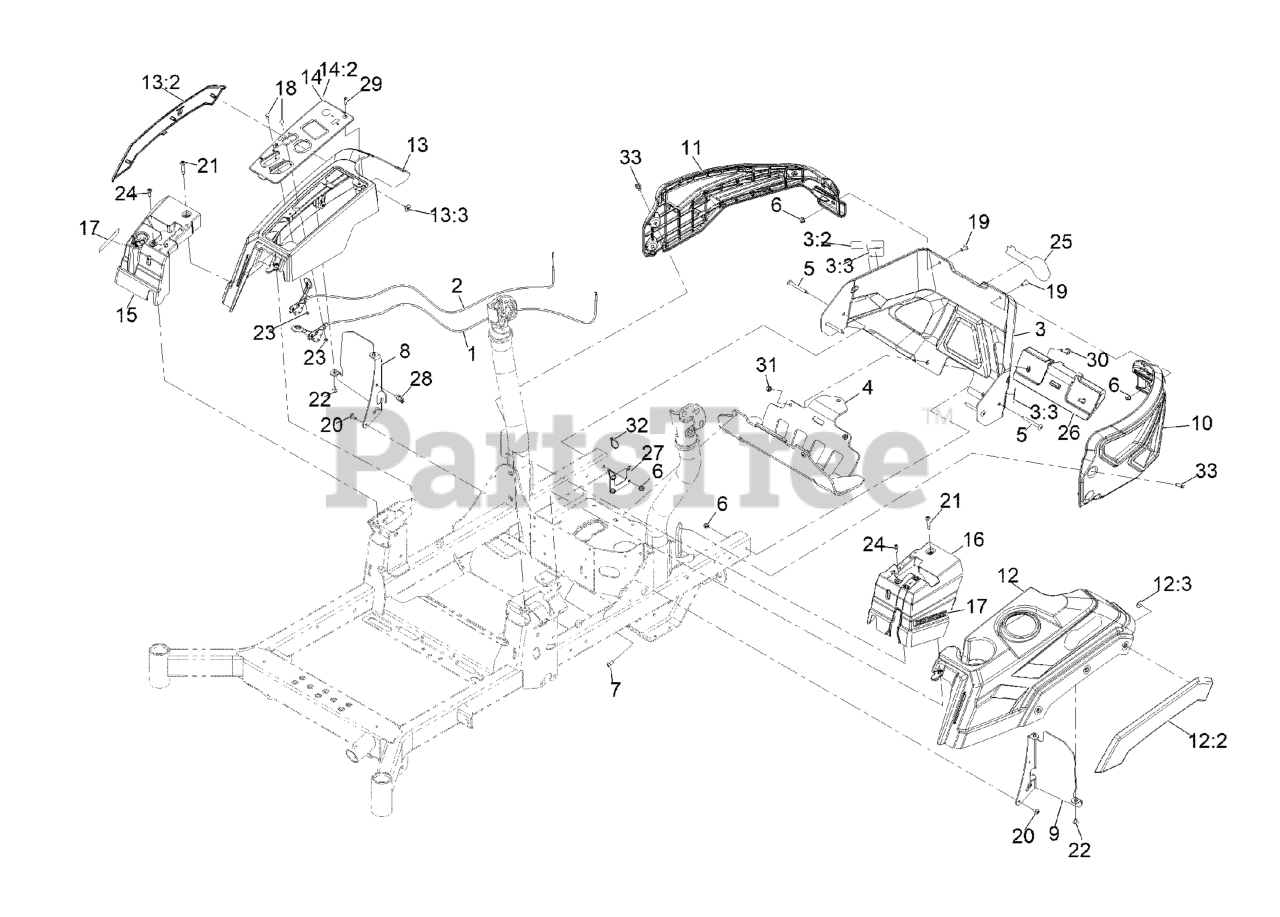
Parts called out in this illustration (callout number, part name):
1	CABLE, THROTTLE CONTROL
2	ASM,CHOKE CABLE
3	ASM, Rear Guard W/ Decals
3:2	DECAL-ARRESTOR, SPARK
3:3	DECAL-WARNING
4	GUARD, MUFFLER [BLACK]
5	SCREW-TORX
6	NUT-HF, NI
7	SCREW, TAPTITE
8	Bracket, Pod, Rt
9	Bracket, Pod, Lt
10	GUARD, UPPER, LT
11	GUARD, UPPER, RT
12	ASM, Pod Lt
12:2	Fender, Lt
12:3	Screw-Torx
13	ASM, POD RT
13:2	Fender, Rt
13:3	Screw-Torx
14	ASM-Control Panel W/Decal
14:2	DECAL-CONTROL PANEL
15	Cover, Motion Control, Rt
16	Cover, Motion Control, Lt
17	DECAL-X-SERIES
18	BOLT-CARR
19	SCREW-TORX
20	SCREW-TORX
21	SCREW-SHOULDER
22	SCREW-TORX
23	NUT-LOCK, NI
24	SCREW-SHOULDER
25	DECAL, EXMARK LOGO
26	WEIGHT, REAR
27	BRACKET, CABLE MOUNT
28	CLIP-TIE
29	Screw-Plastic, HWH
30	SCREW-HHF
32	TIE-CABLE
33	SCREW-SHOULDER
